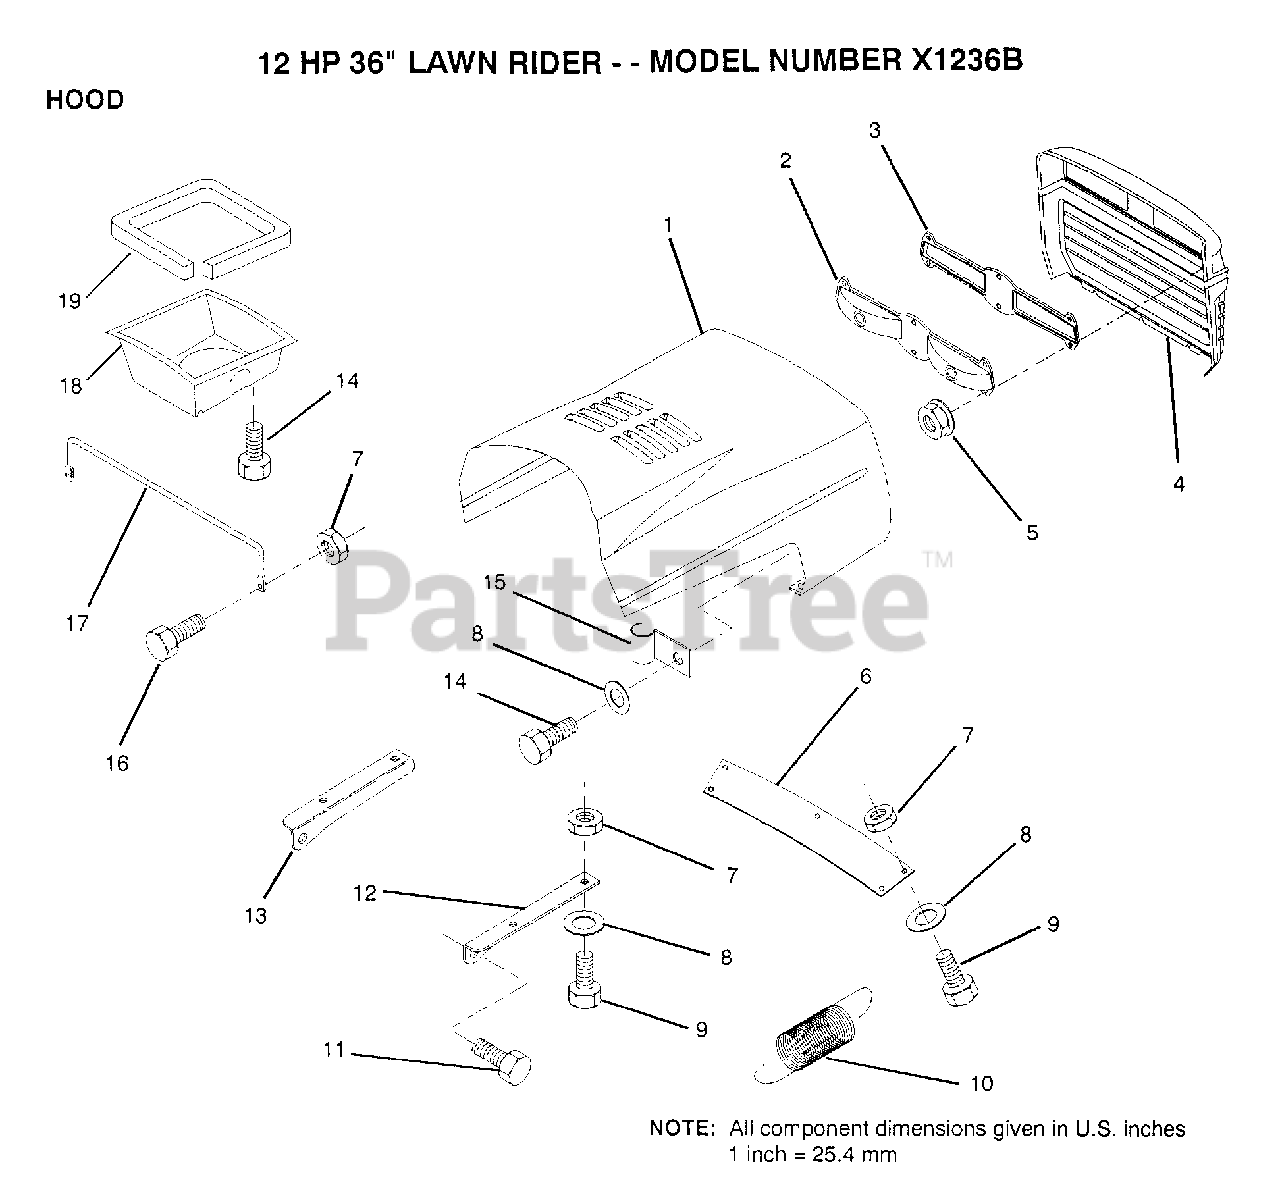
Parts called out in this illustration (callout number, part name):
5	NUT
7	NUT
8	WASHER
9	BOLT
10	EXT SPRING
12	BRKT HOOD RH
13	BRKT HOOD LH
15	CLIP T
17	"BRACE,HOOD"
18	"DUCT,AIR"
19	FOAM STRIP LT
